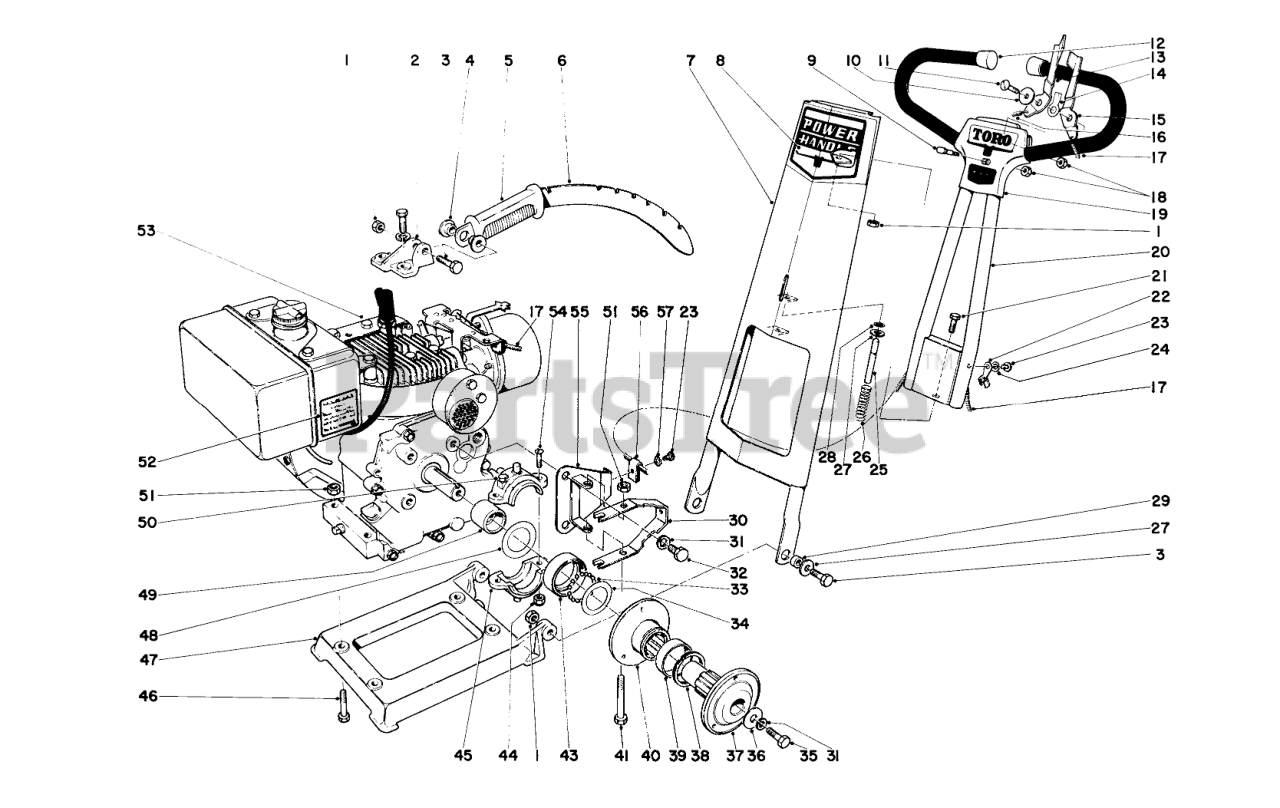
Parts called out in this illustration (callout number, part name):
1	Nut
2	Handle Adjustment Bracket
3	SCREW-HH
4	GROMMET
5	Grip Handle
6	Bar Adjustment
7	Lower Handle Assembly (Incl. Ref. Nos. 8 & 25 thru 28)
8	Decal
9	Screw
10	WASHER CONTROL PIVOT
12	Button Plug
13	Clutch Lever
14	Washer
15	Throttle Lever
16	CLUTCH CONTROL ASM
17	Throttle Control Assy.
18	NUT-LOCK, NI
19	Escutcheon Plate
20	Upper Handle (Incl. Ref #12)
21	SCREW-HH
22	Clamp
23	SCREW-PPH
24	WASHER-LOCK
26	SPRING
27	WASHER-PLAIN
28	RING-RETAINING, EXT
29	Grommet
30	Shift Fork
31	WASHER-LOCK
32	SCREW-HH
33	Ball
34	Check Washer
35	SCREW-HH
36	Washer
37	Body, Clutch
38	1-1/2X048 EX MED RING
39	IDLER BUSHING
40	Sliding Flange
41	SCREW-HH
43	Ball Race
44	NUT-LOCK
45	Slip Ring Kit (Incl. Ref. #50)
46	10 Capscrew
47	Engine Base
48	Washer-Thrust
49	Inner Ball Race
50	OILER
51	NUT-LOCK NI
52	Decal
53	Engine
54	SCREW
55	Bracket Mount
56	3/16 SUPPORT
57	WASHER-LOCK, EXT
